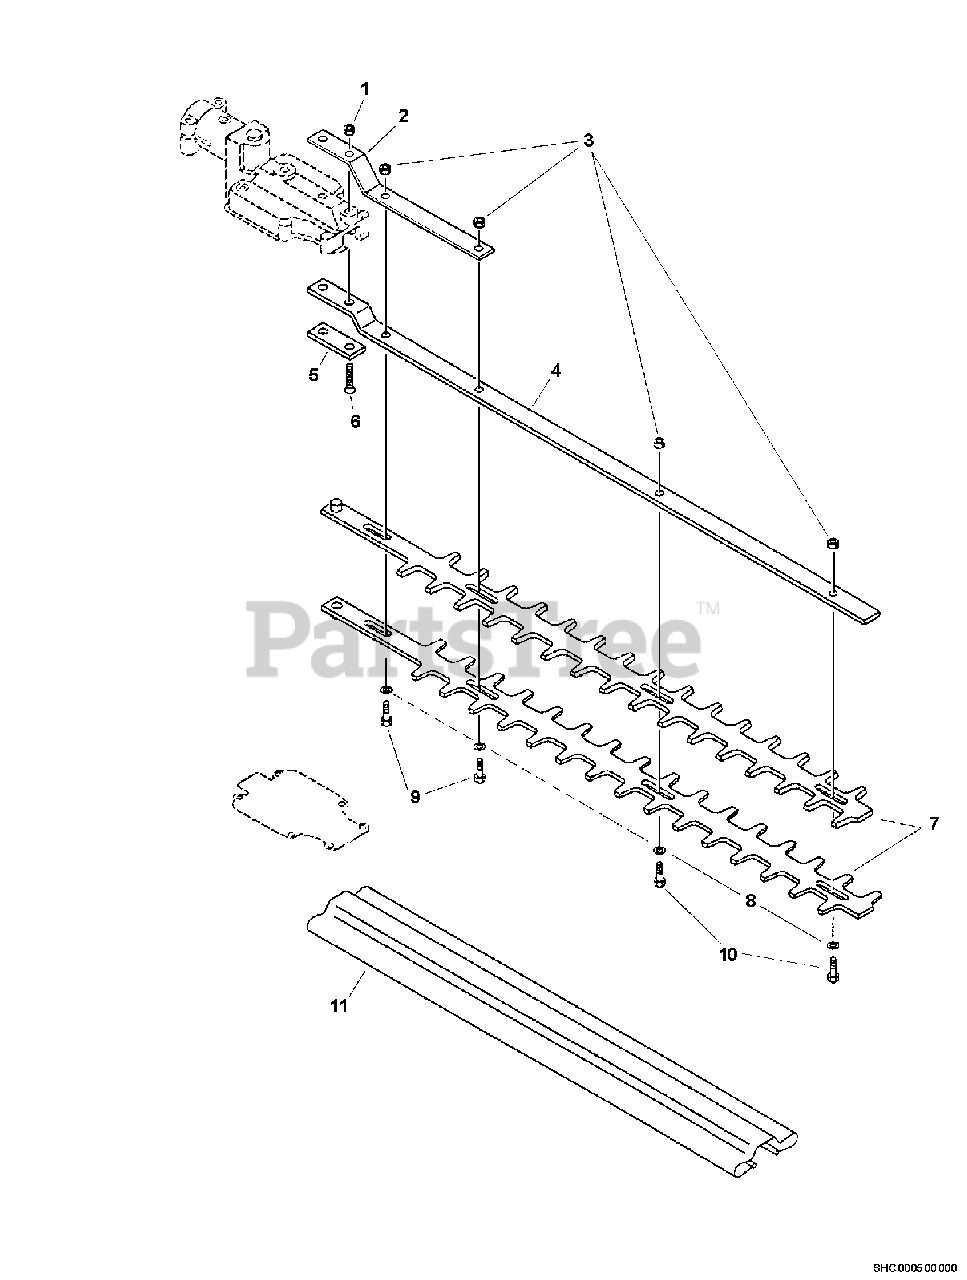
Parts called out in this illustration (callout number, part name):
1	NUT, HEX M6
2	BRACKET, BLADE
4	SUPPORT, BLADE 20"
5	PLATE, EYE
6	SCREW 6×35
7	BLADE - 20"
8	WASHER 6.5×15.5×0.6
9	BOLT 6×20
11	COVER, BLADE
